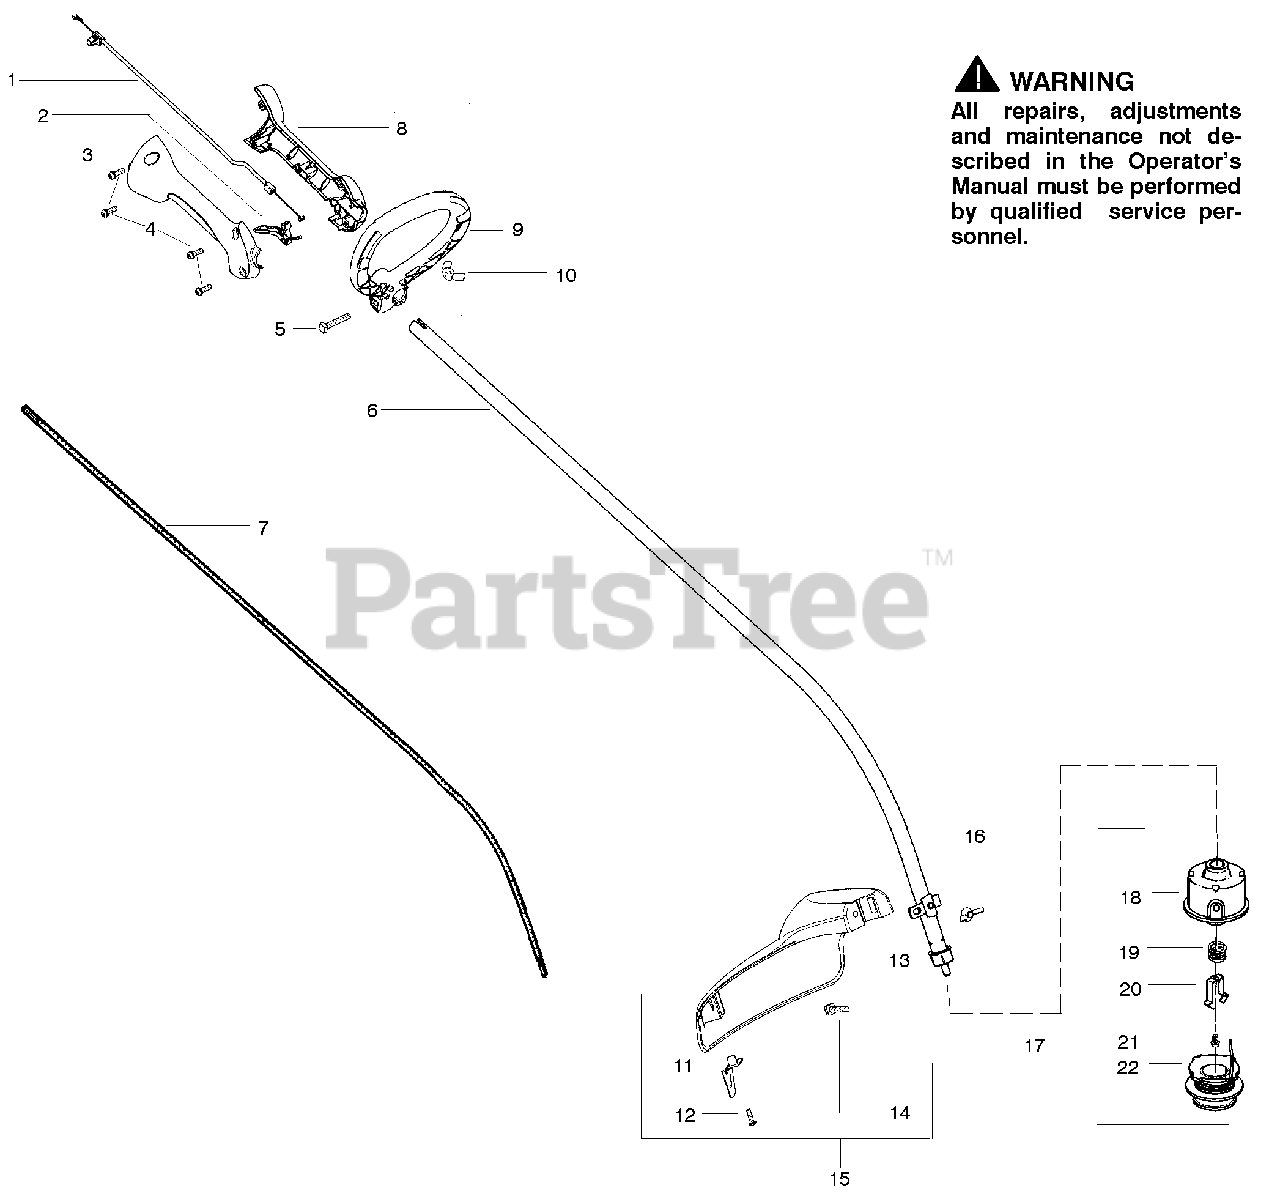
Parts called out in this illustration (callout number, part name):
1	Assy-Throttle Cable
3	Throttle Hsg. (Right)
4	Screw-Throttle Hsg.
6	Assy-Drive Shaft Hsg.
7	Shaft- Flex
8	Throttle Hsg. (Left)
9	Assy-Handle
10	Wingnut
11	Kit - Line Limiter
12	Screw-Line Limiter
13	Dust Cup
15	Kit-Shield Assy
16	Wingnut
17	Accy-TNG IV Cutting Head
18	Assy-Hub
19	Spring-Compression
20	Clip-Retainer-Head
22	Accy- Spool w/Line
